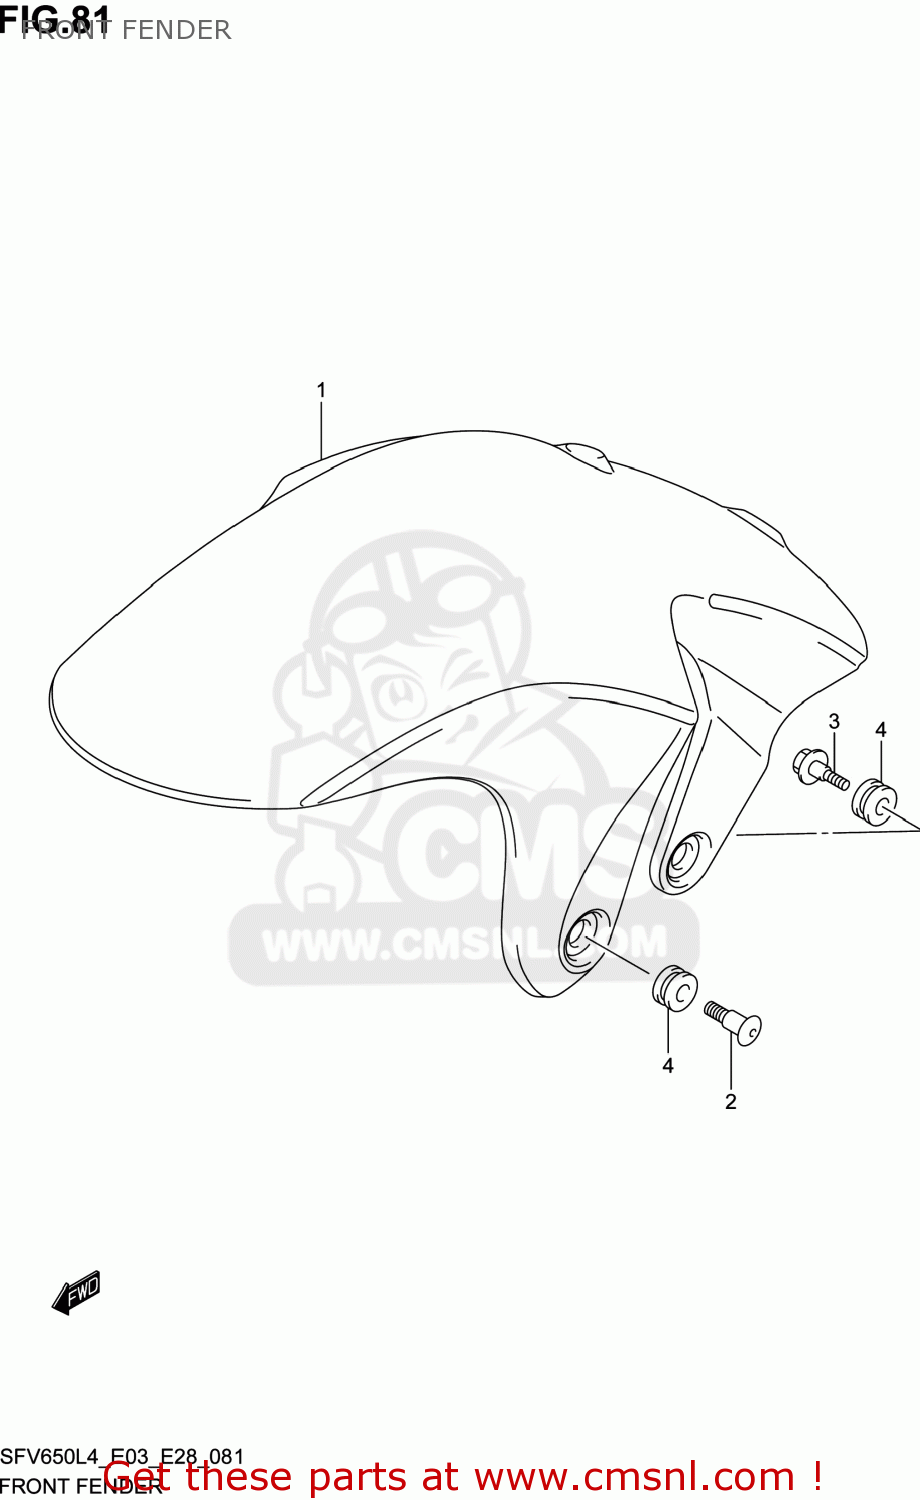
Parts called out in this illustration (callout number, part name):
1	FENDER,FR
2	SCREW(6X16)
3	BOLT(6X19)
4	CUSHION
